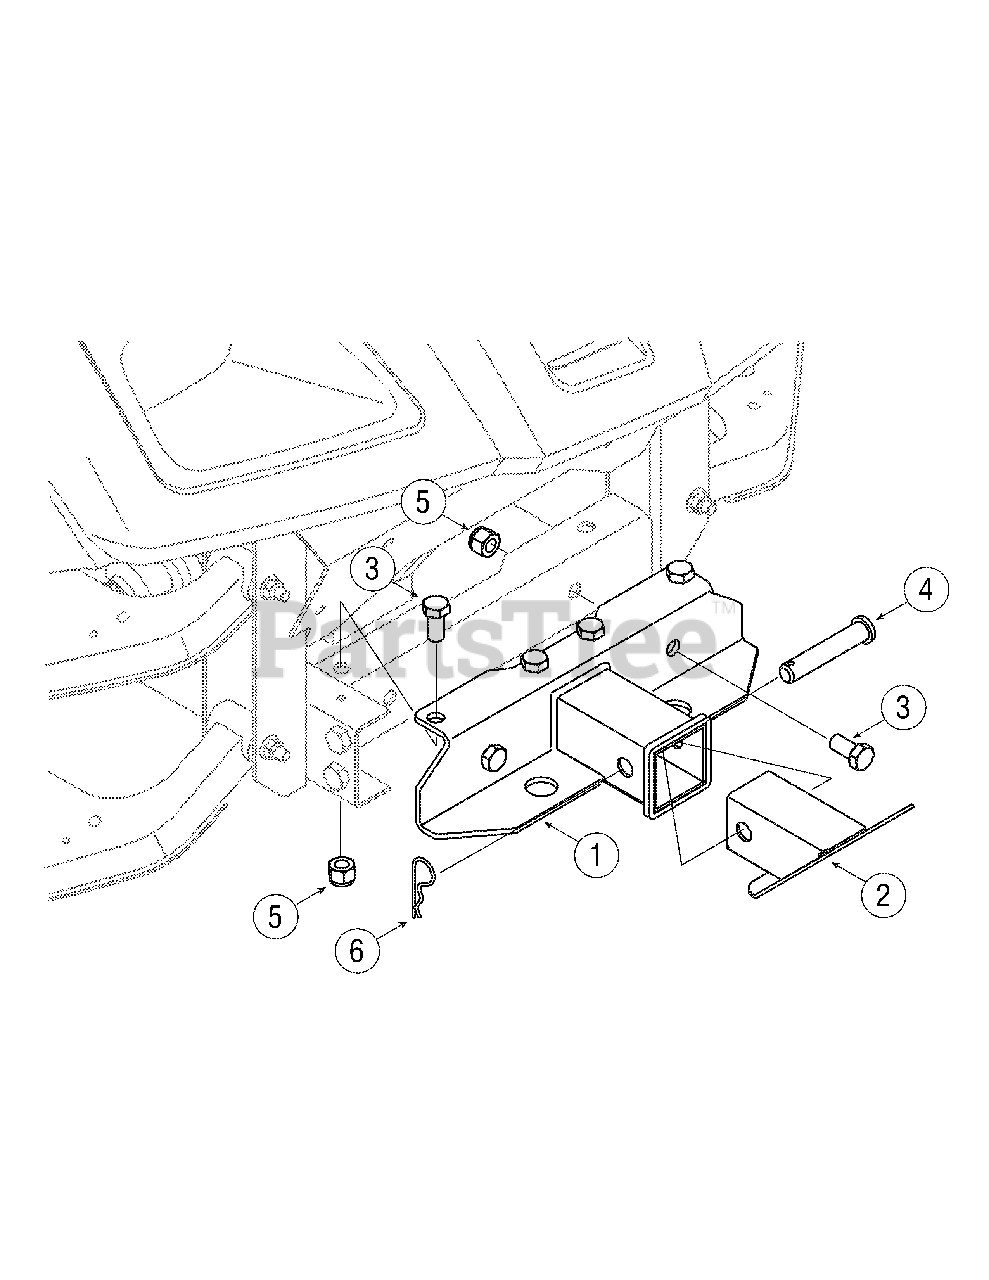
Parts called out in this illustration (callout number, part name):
1	Hitch Assembly, Receiver
2	Cvr Assembly, Hitch
3	Hhcs, 1/2-13 x 1.00
4	Pin, Clevis, .625 Dia. X 3.075 Lg.
5	Nut, Hexlk, 1/2-13
6	Int. Cotter Pin
